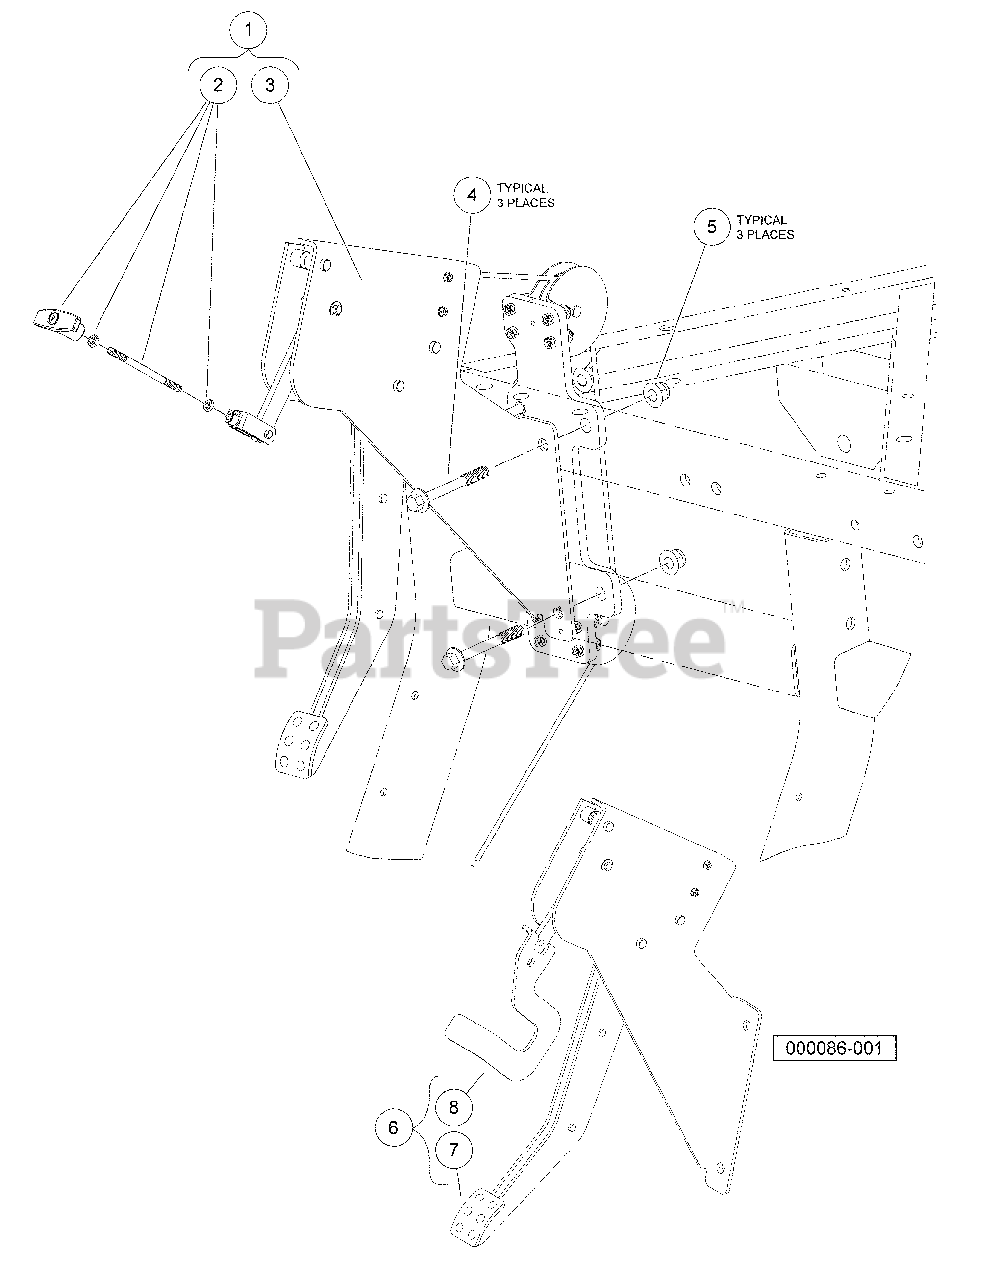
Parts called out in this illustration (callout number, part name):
1	Pedal Asm, Brake, Park
2	Kit, Handle, Brake, Park
3	Pedal, Brake, Park
4	Bolt Flanged Head, M8 X 1.25 X 65
5	Lock Nut, Flg M8 X 1.25 Nylon
6	Asm, Pedal, Brake, Hard
7	Pedal, Brake, Park
8	Handle, Release, Park Brake
